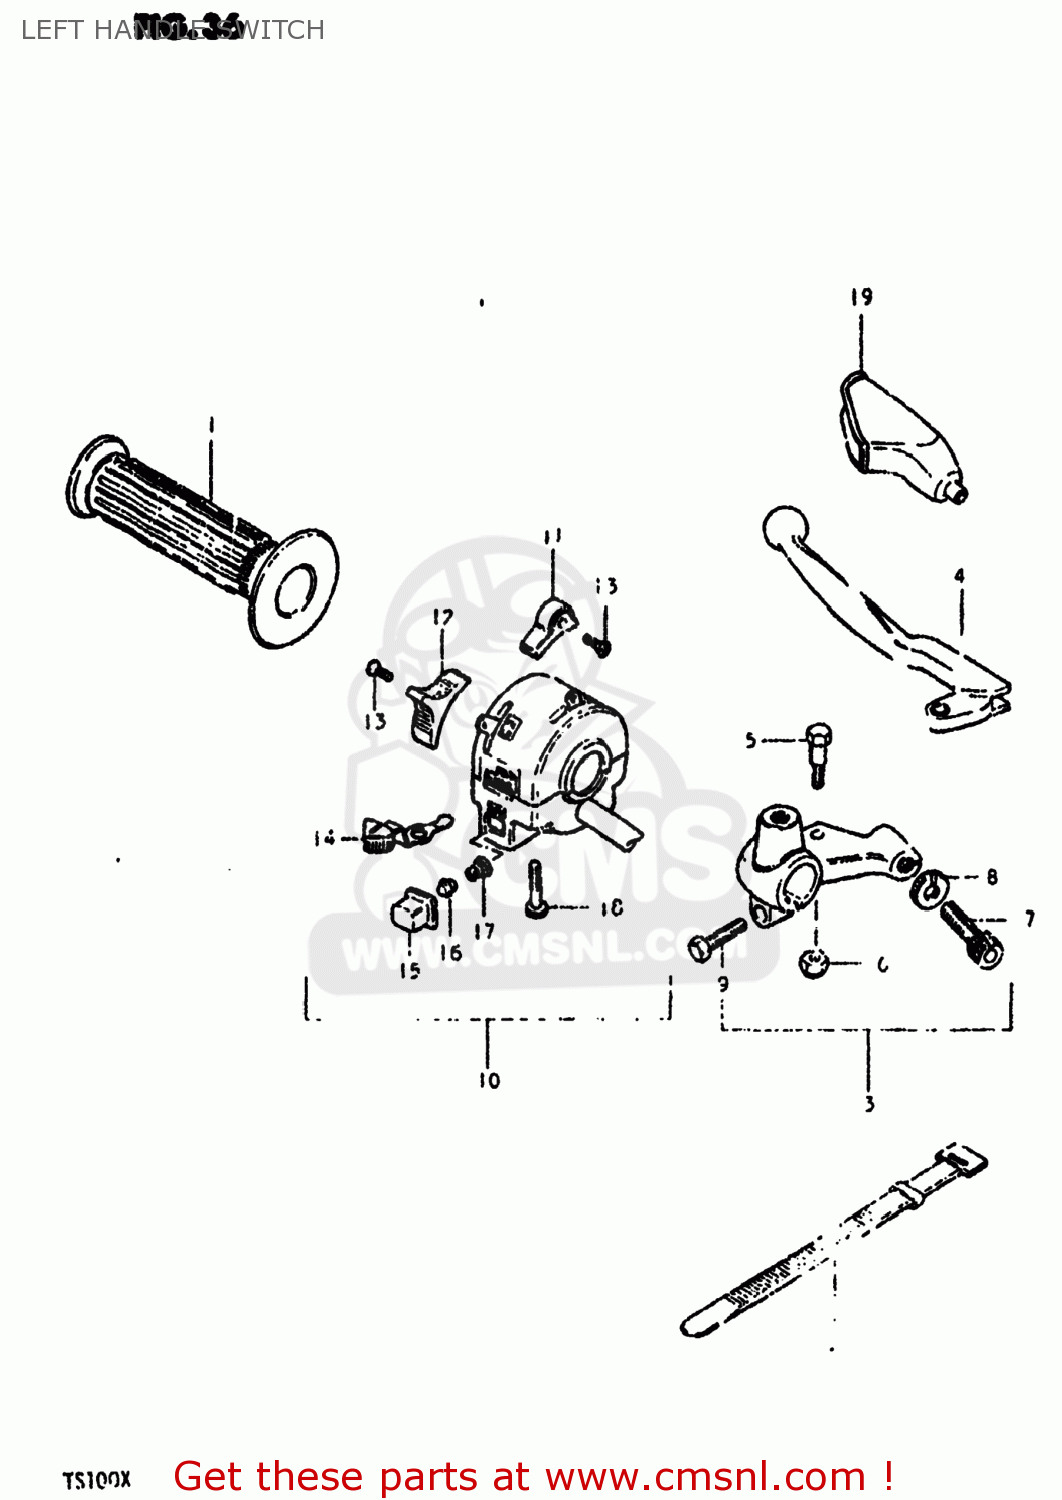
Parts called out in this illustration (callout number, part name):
1	GRIP,L
2	CLAMP(L:120)
3	LEVER ASSY,CLUTCH
4	LEVER,CLUTCH
5	BOLT,LEVER
6	NUT 6MM
7	ADJUSTER,CABLE
8	NUT,CABLE ADJUSTER
9	BOLT
10	SWITCH ASSEMBLY,HANDLE,LEFT
11	KNOB, STOPPER
12	KNOB,DIMMER SWITCH
13	SCREW
14	KNOB,TURNSIGNAL
15	BUTTON,HORN
16	CONTACT
17	SPRING
18	SCREW
19	COVER,CLUTCH LEVER
